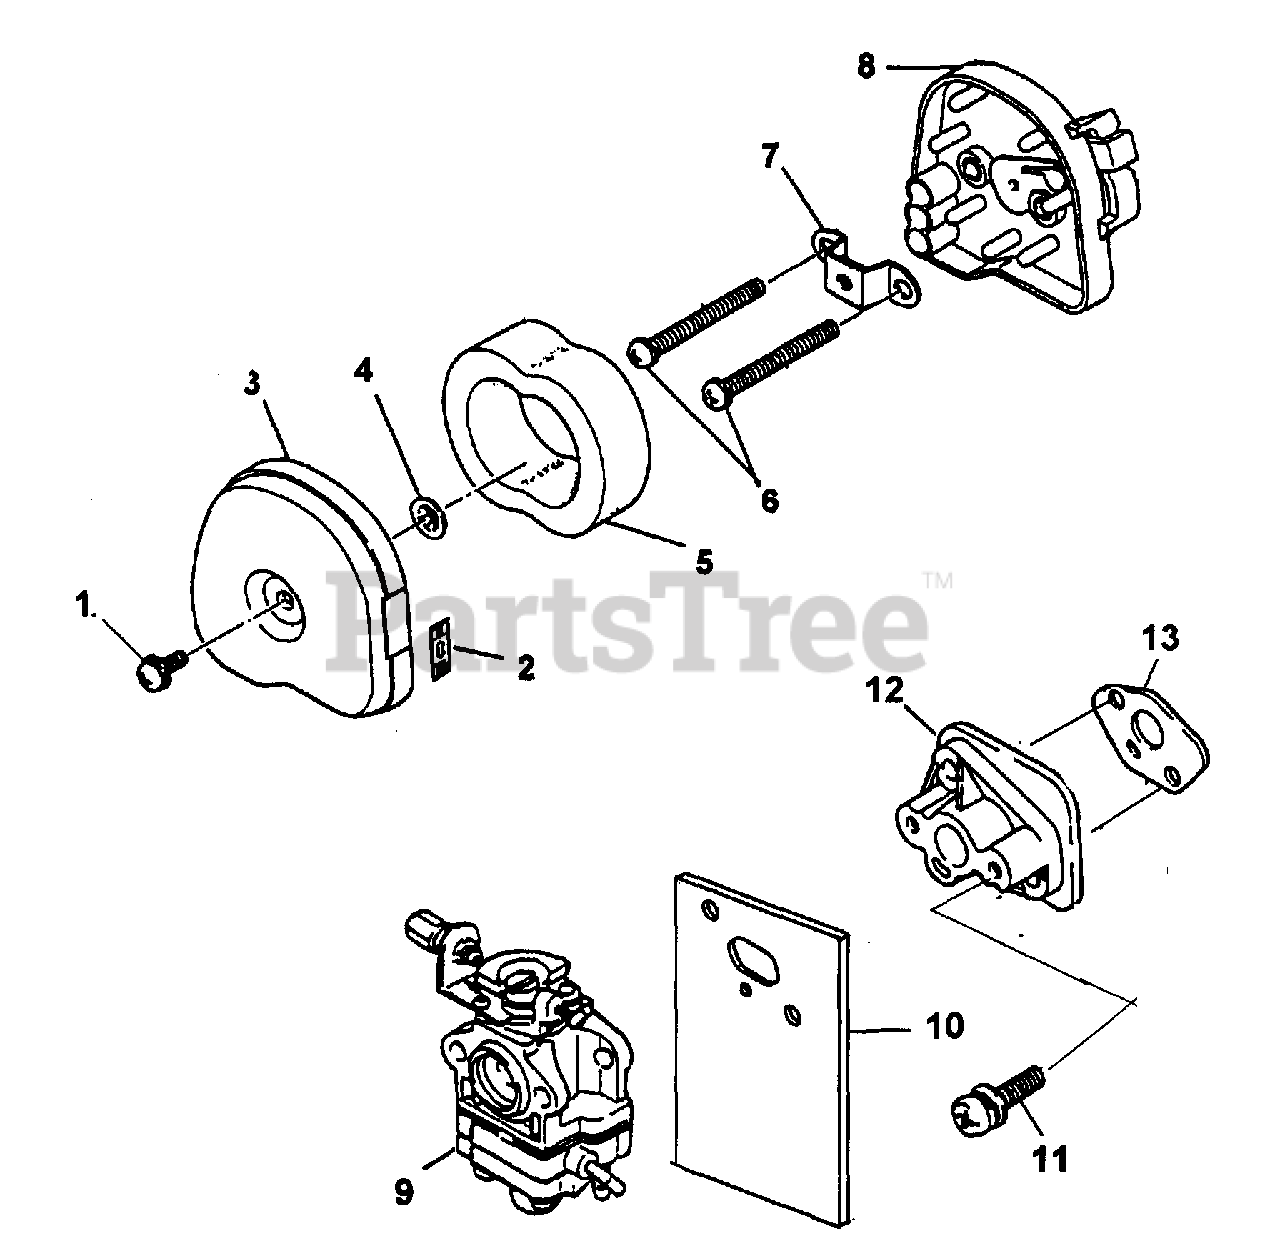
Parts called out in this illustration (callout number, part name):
1	SCREW & WASHER
2	LABEL, NAME
3	COVER, AIR CLEANER
5	ELEMENT AIR CLEANER
6	SCREW & WASHER
7	BRACKET
8	CASE, CLEANER
9	CARBURETOR ASSY
10	GASKET, CARBURETOR
11	SCREW & WASHER
12	INSULATOR
13	GASKET INSULATOR
